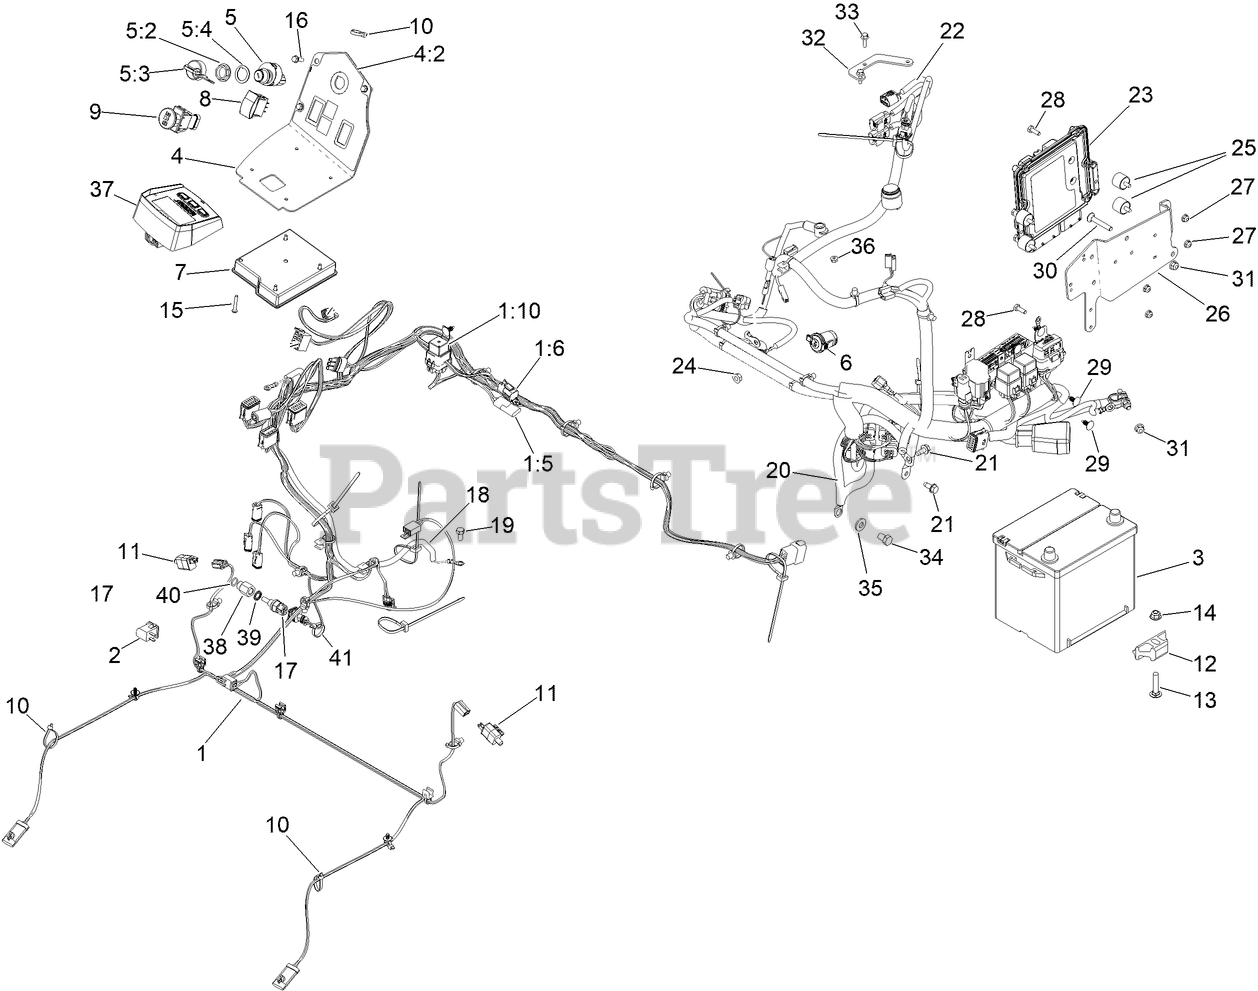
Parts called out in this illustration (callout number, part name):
1	HARNESS-WIRE, MAIN
1:5	CAP-PLUG
1:6	CAP-PLUG, 6 WAY
1:10	RELAY-MINI
2	SWITCH-BAIL
3	BATTERY-DRY
4	CONSOLE ASM
4:2	DECAL-CONSOLE
5	IGNITION SWITCH ASM
5:2	NUT-MOUNTING
5:3	IGNITION KEY SET
5:4	WASHER-BACKUP
6	PORT-POWER, 12V
7	MODULE-MCU
8	SWITCH
9	SWITCH-PTO, SEALED
10	TIE-CABLE
11	SWITCH
12	RETAINER-BATTERY
13	SCREW-CARR
14	NUT-HF, NI
15	SCREW-PPH
16	SCREW-HWH
17	SENSOR-TEMPERATURE
18	HARNESS-WIRE, JUMPER
19	BOLT
20	CABLE-BATTERY
21	SCREW-HWHTF
22	HARNESS-WIRE, YANMAR
23	CONTROLLER-ENGINE
24	NUT-HF
25	MOUNT-CYLINDRICAL
26	MOUNT-CONTROL UNIT, ENGINE
27	NUT-HF
28	SCREW-HH
29	PLUG-PLASTIC
30	BOLT-CARR
31	NUT-HF, NI
32	BRACKET-WIRING, ENGINE
33	SCREW-HHF
34	SCREW-HH
35	WASHER-BELLEVILLE
36	NUT-HF
37	MODULE-HORIZON
38	FITTING-STR, 6MORB-M12, STL, CZ
39	O-RING
40	WASHER-SEAL, M12
41	TIE-CABLE
